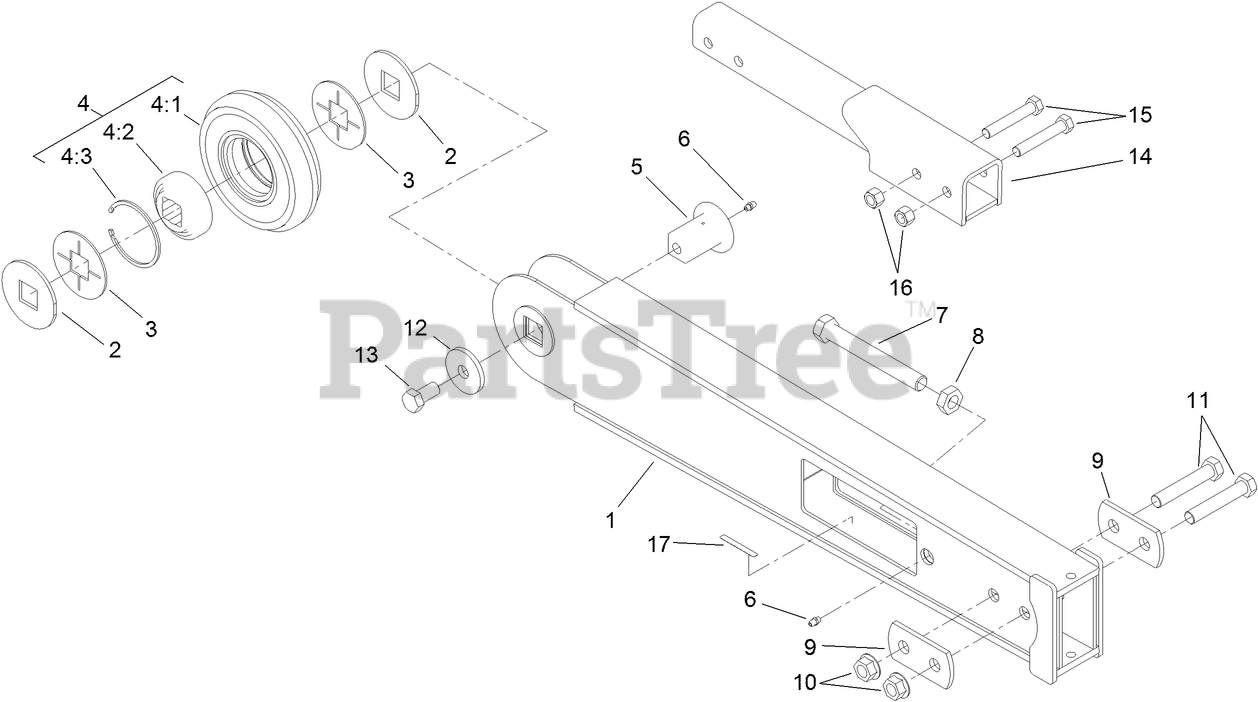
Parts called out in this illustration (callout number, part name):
1	BOOM ASM
2	CAP-ROLLER
3	SPACER-ROLLER
4	TRENCHER ROLLER ASM
4:1	ROLLER-NOSE
4:2	BEARING
4:3	RING-RETAINING
5	AXLE-ROLLER
6	FITTING-GREASE
7	BOLT-ADJUSTMENT
8	NUT-JAM
9	PLATE-SUPPORT
10	NUT-FLANGE
11	SCREW-HH
12	WASHER
13	SCREW-HH
14	EXTENSION-SAFETY BAR
15	SCREW-HH
16	NUT-HEX
17	DECAL-WARNING
